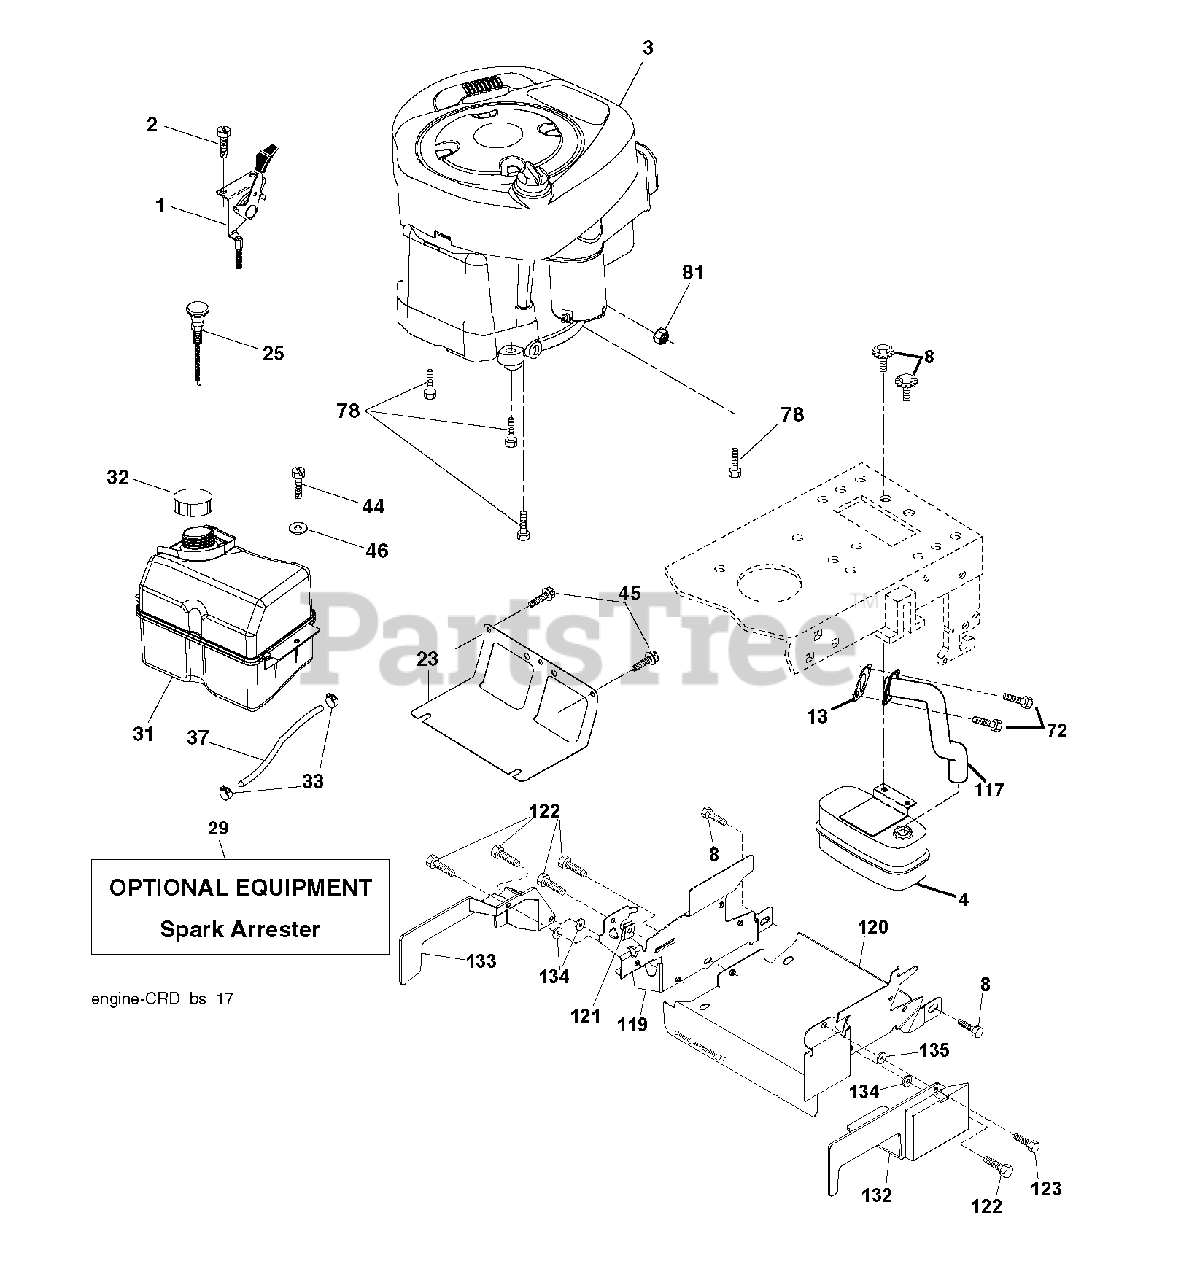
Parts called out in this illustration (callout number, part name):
1	CONTROL TH/CH FLAG
2	SCREW
4	MUFFLER.SINGLE.CYL.KOHL/B&S
8	BOLT, 5/16-18 X 1 3/4
13	REPL BY 532 27 22-93
23	SHEILD.BROWNING.DBR.GUARD
29	ARRESTER SPARK (OPTIONAL)
32	FUEL CAP
33	HOSE CLAMP
37	LINE.FUEL.20
44	SCREW HEXWSHR 1/4-20X3/4
45	SCREW, 3/8-16X3/4
72	SCREW.SOCKET HD.5/16-1
78	SCREW.3/8-16
81	NUT
117	EXHAUST.TUBE.B&S.
122	SCREW.1/4-20X5/8
123	SCREW, 5/16-18 X 1/2
134	PALNUT 1/4
